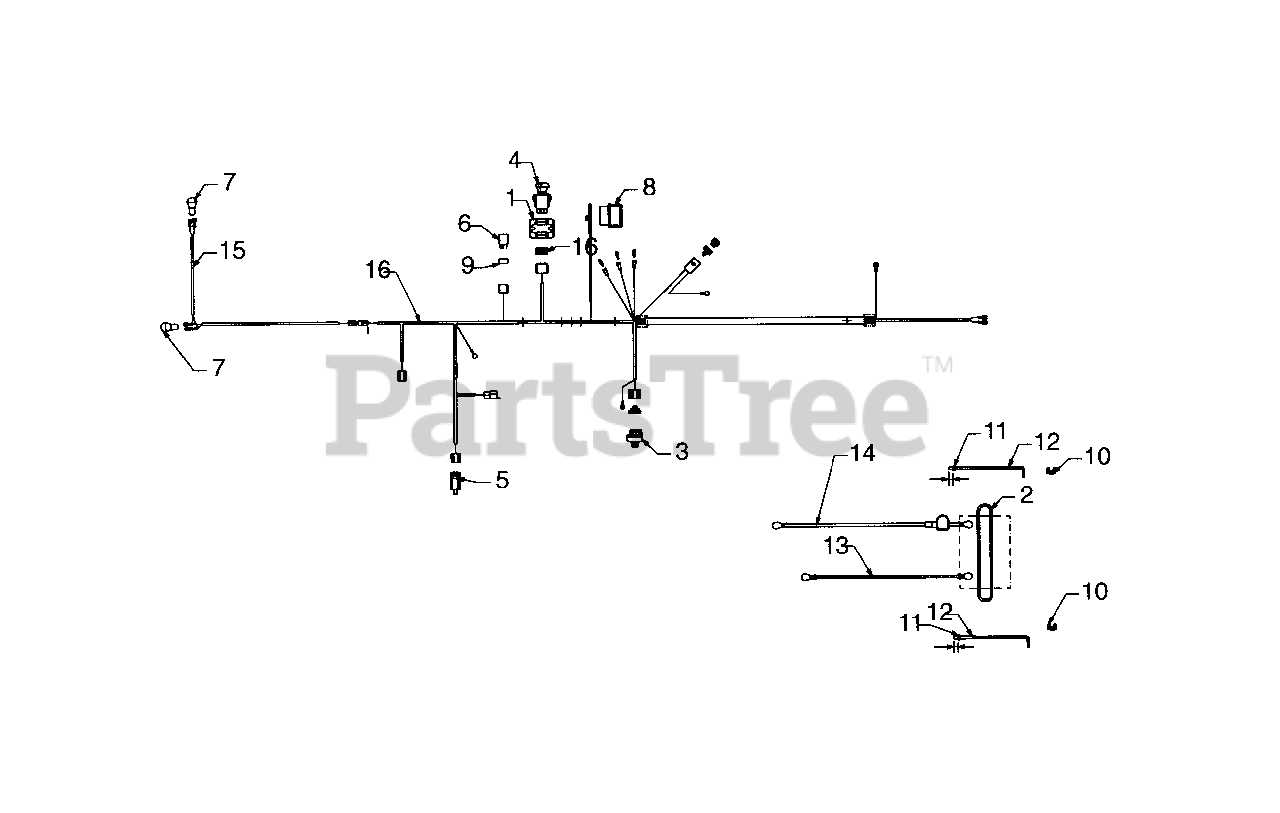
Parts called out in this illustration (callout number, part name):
1	PTO Bracket
2	Battery Hold Down
3	Ignition Switch
4	Electric PTO Swtich
5	Safety Switch
6	Relay
7	Light Bulb
8	Ammeter
9	Relay Gasket
10	Wing Nut 1/4-20
11	Lock Nut 1/4-20
12	Battery Hold Down Rod
13	Wire Asm. Black #8 17" Lg.
14	Wire Asm. Red w/Boot #6 x 20" Lg.
15	Wire Asm. Headlight
16	Wire Harness Ass'y
